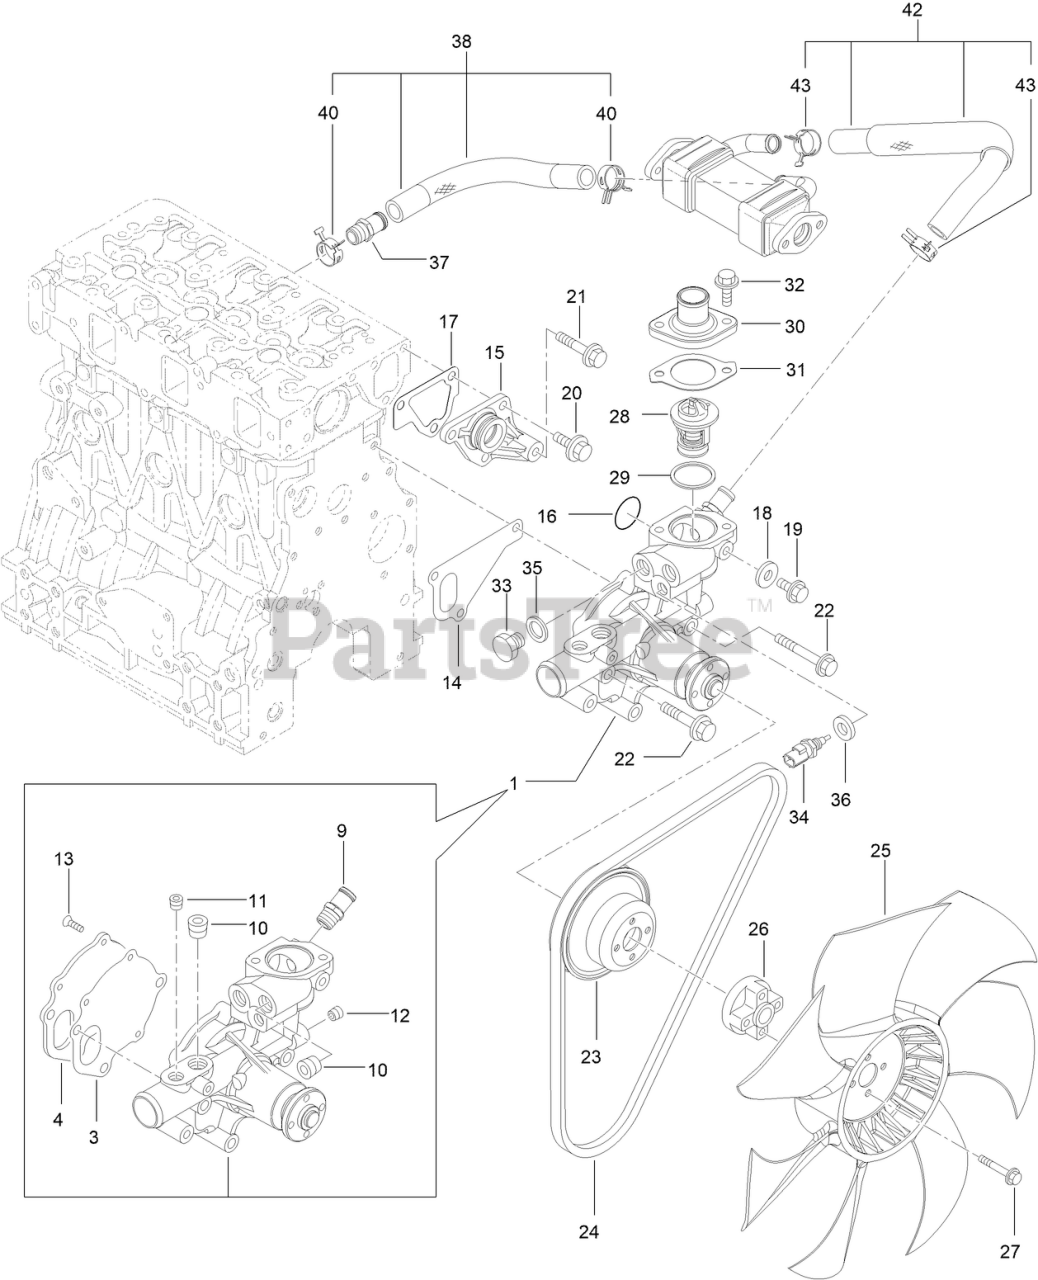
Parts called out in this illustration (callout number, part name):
1	WATER PUMP ASM
3	GASKET
14	GASKET
16	O-RING
17	GASKET
18	GASKET
20	BOLT
23	V-PULLEY
24	V-BELT
26	SPACER
28	THERMOSTAT
29	GASKET
31	GASKET
34	SENSOR-THERMOSTAT, CW
35	GASKET
36	WASHER-SEAL
38	WATER IN PIPE ASM
40	CLIP-HOSE
42	CW PIPE ASM
43	CLIP-HOSE
